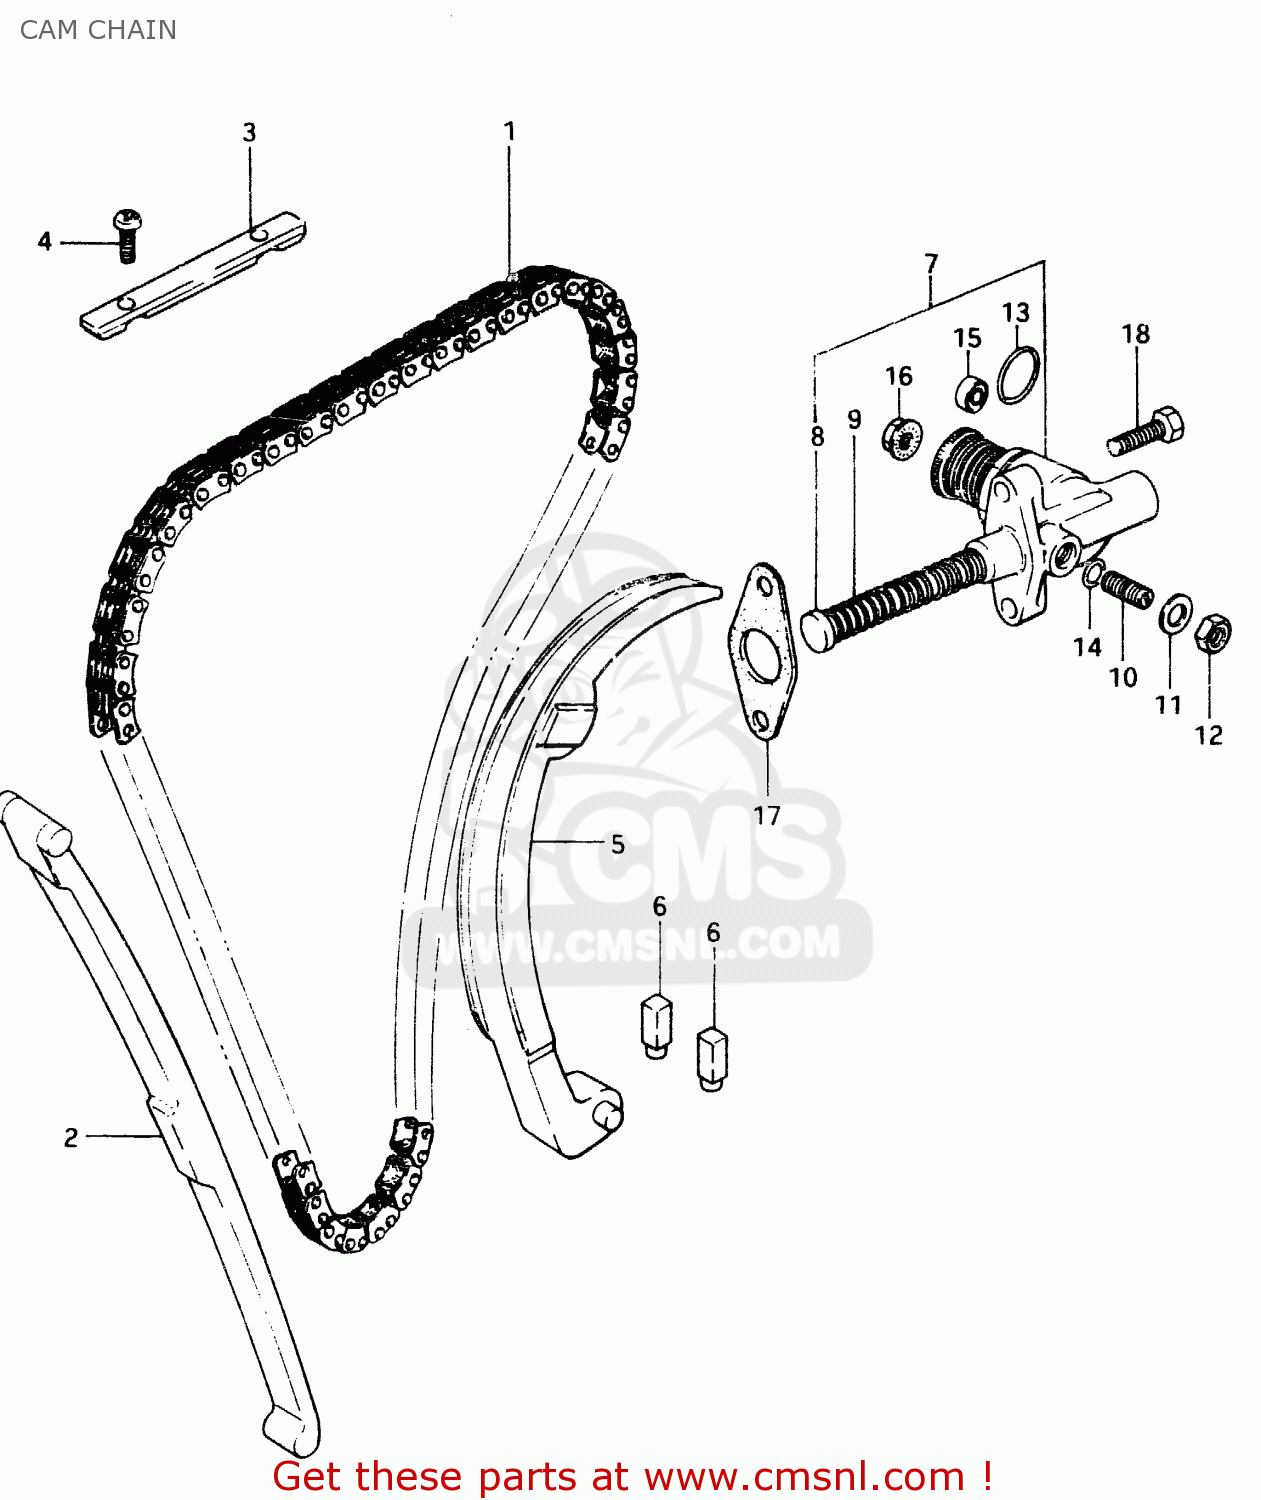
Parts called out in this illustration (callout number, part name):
1	CHAIN, CAM SHAFT DRIVE
2	GUIDE,CAM CHAIN NO.1
3	GUIDE,CAM CHAIN NO.2
4	SCREW
5	TENSIONER,CAM CHAIN
6	CUSHION,CAM CHAIN TENSIONER
7	ADJUSTER ASSY,TENSIONER
8	ROD,PUSH
9	SPRING
10	SCREW,TENSIONER ADJUST
11	WASHER,8.5X16X
12	NUT
13	O-RING
14	O-RING
15	OIL SEAL
16	NUT
17	GASKET,TENSIONER ADJUSTER (MCA)
18	SCREW
